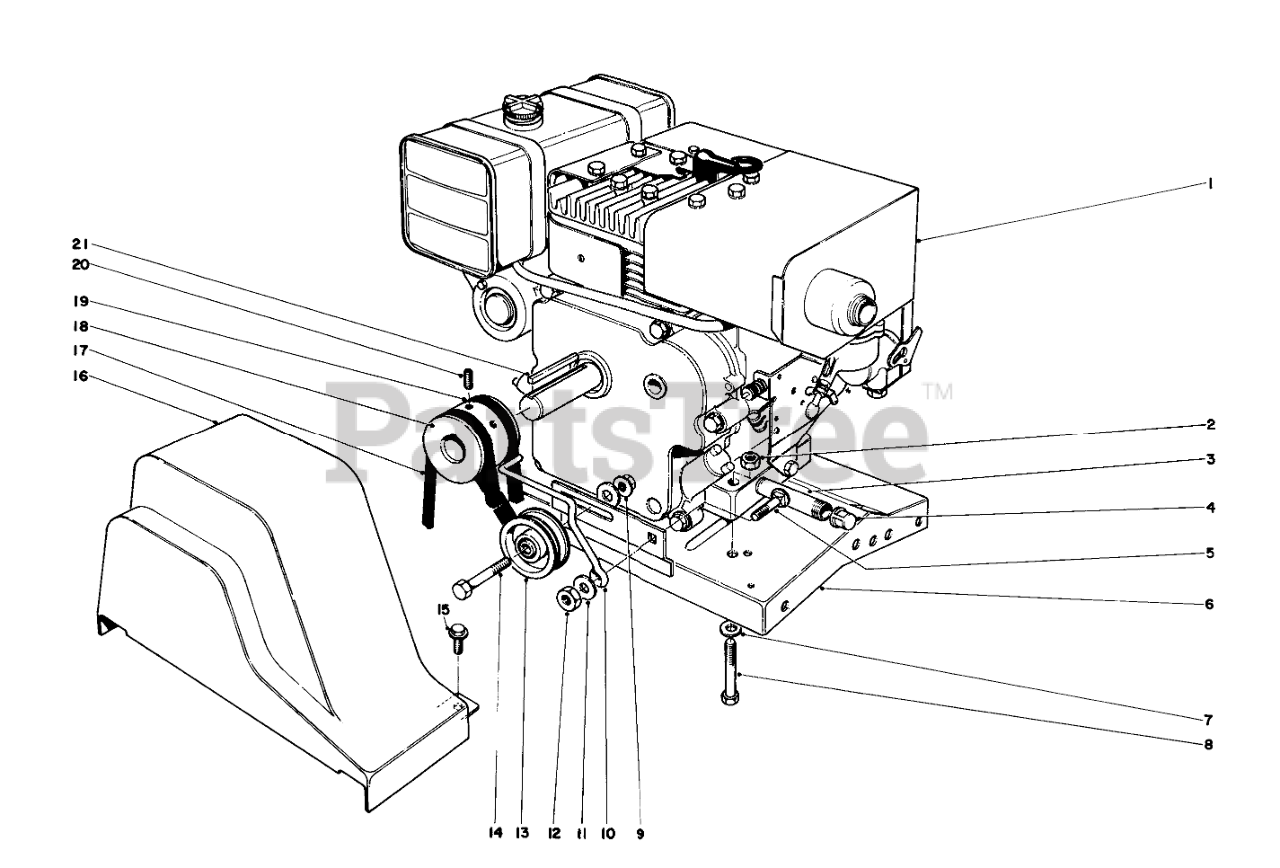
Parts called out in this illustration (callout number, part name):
1	Engine
2	NUT-LOCK, CONE
3	NIPPLE-PIPE
4	CAP-PIPE
5	SCREW-CARR
6	Engine Base
7	WASHER-PLAIN
8	SCREW-HH
9	NUT-HHF, WHIZ
10	BELT GUIDE
11	WASHER-FLAT
12	NUT-HEX
13	PULLEY-IDLER
14	SCREW-HH
15	SCREW-HWH
16	BELT GUARD
17	V-Belt
18	Pulley
19	V-BELT
20	Screw-Set
